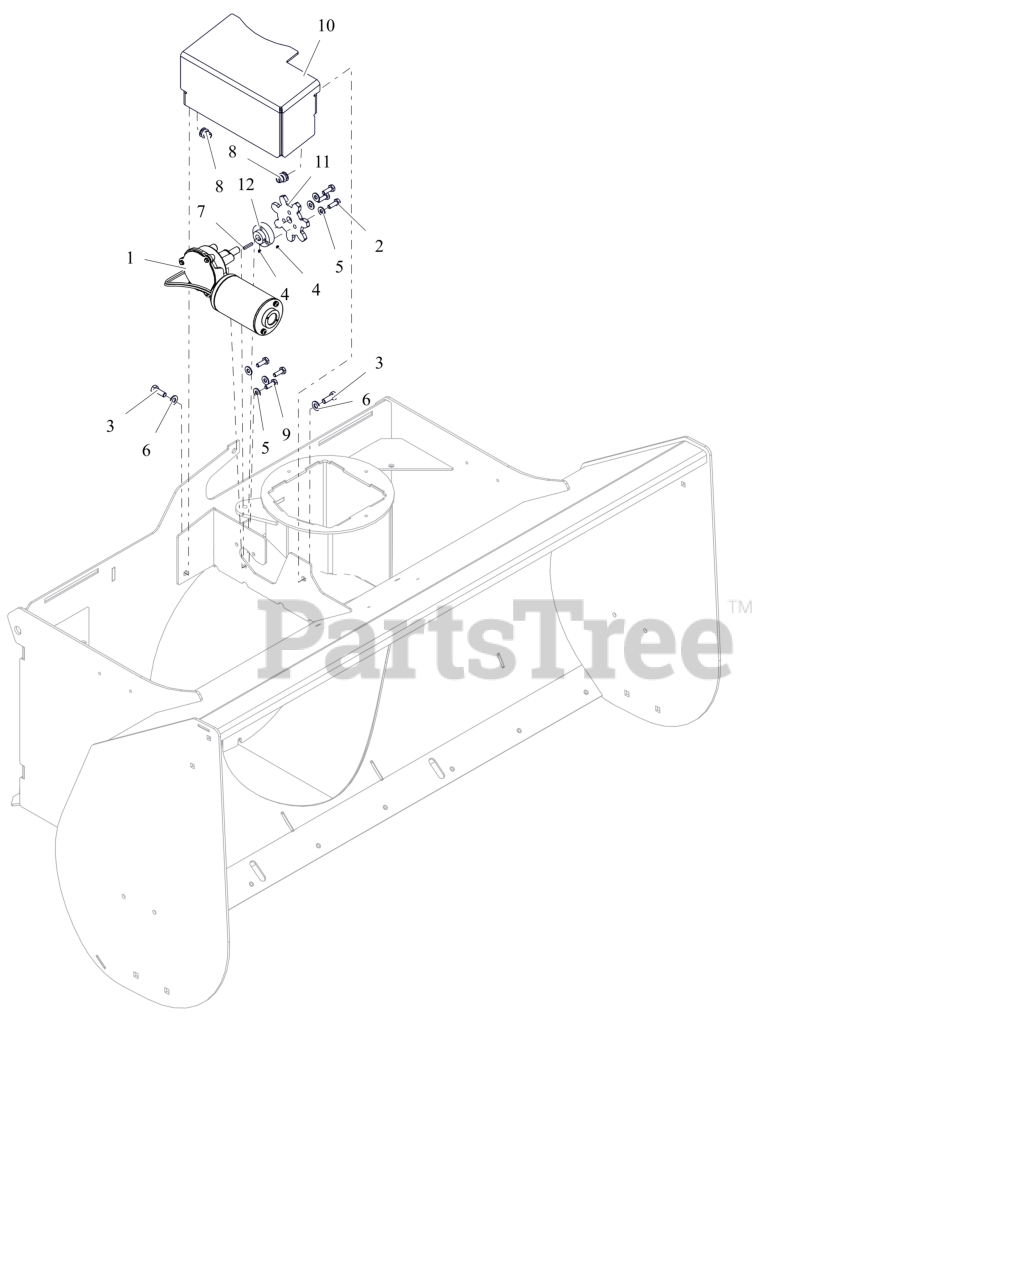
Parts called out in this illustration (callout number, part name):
1	MOTOR, GEAR - CHUTE ROTATION
2	BLT, HEX .25-20X.75 G5 ZCC
3	BLT, HEX .31-18X.875 G5 ZCC
4	SET, SCR 10-24 X .188 W/ PATCH
5	WSHR,FLT .281X.625X.065 ZCC
6	WSHR,FLT .344X.688X.065 ZCC
7	KEY, .125 SQ. X .8125
8	RVT, HEX 5/16-18 SHORT
9	BOLT, HEX 0.250-28X0.75 GR5
10	BRKT, MOTOR COVER
11	GEAR, CHUTE DRIVE
12	ADAPTOR, MOTOR SHAFT
